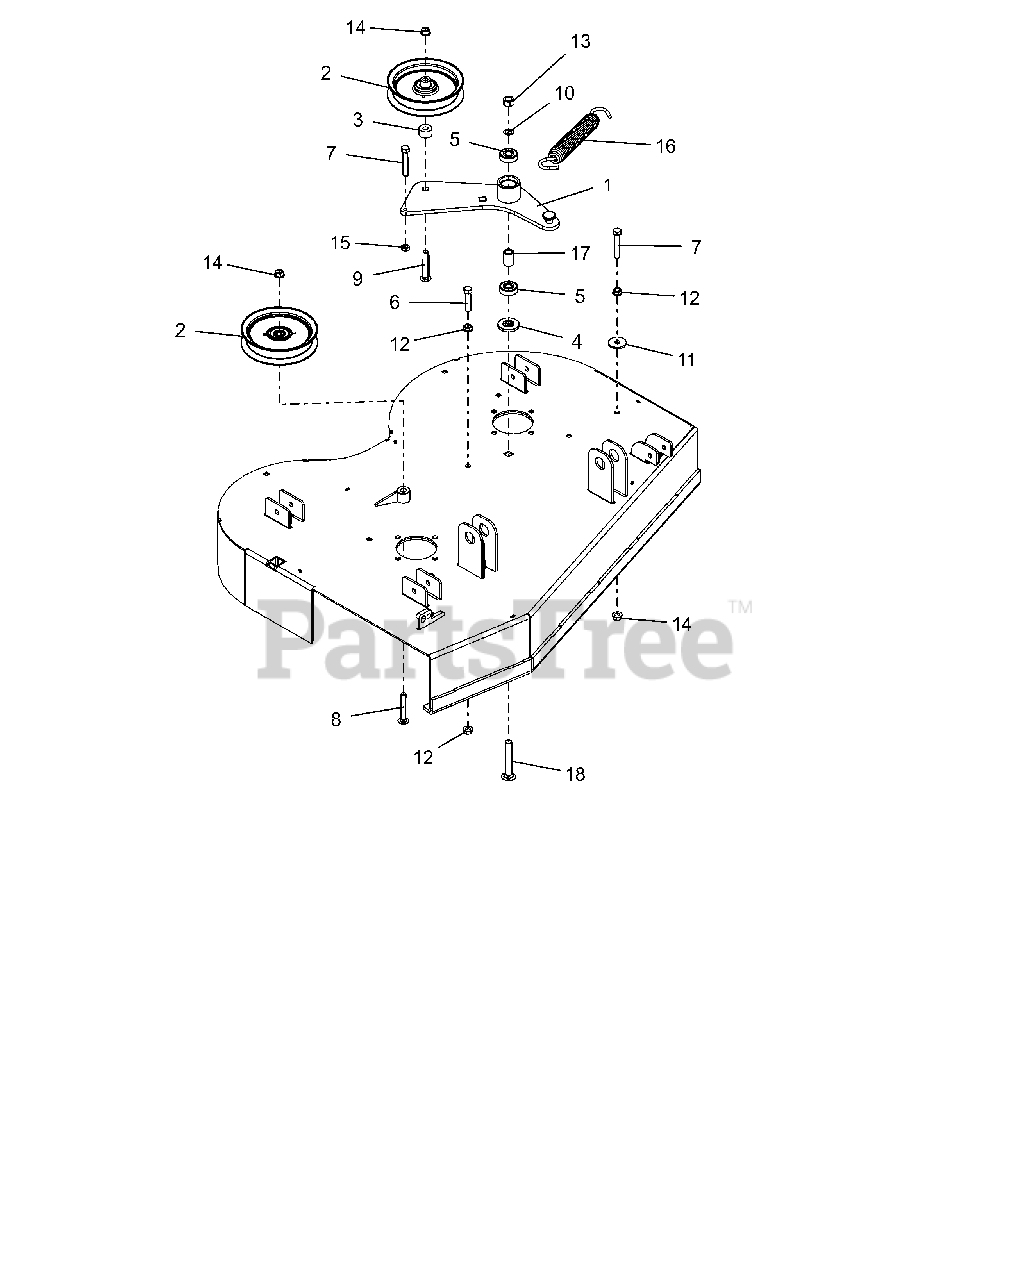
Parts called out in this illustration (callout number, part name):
1	WLDMT, IDLER ARM
2	IDLER, FLAT 5.00"
3	SPACER .390X1.000X.562
4	SPACER, IDLER ARM
5	BRG-BALL .500X1.38X.437
6	BLT, HEX .38-16X1.75F G5 ZCC
7	BLT,HEX .38-16X2.25 G5 ZCC
8	BLT,RHSN .38-16X2.50 G5 ZCC
9	BLT, RHSSN.38-16X2.50 G5 ZCC
10	WASHER, .500X.750X.020 THRUST
11	WSHR,FLT .406X1.375X.135 ZCC
12	NUT, SPNLK-FLG .38-16 G5 ZCC
13	NUT,LK-CTR .50-13 GA ZCC
14	NUT-LK-CTR-FLG .375-16 GF ZCC
15	NUT-JAM .375-16 G2 ZCC
16	SPRING, EXTENSION
17	SPACER .510 X .75 X 1.1485
18	BTL,RHSSN .500-13 X 3.25 G5 ZCC
